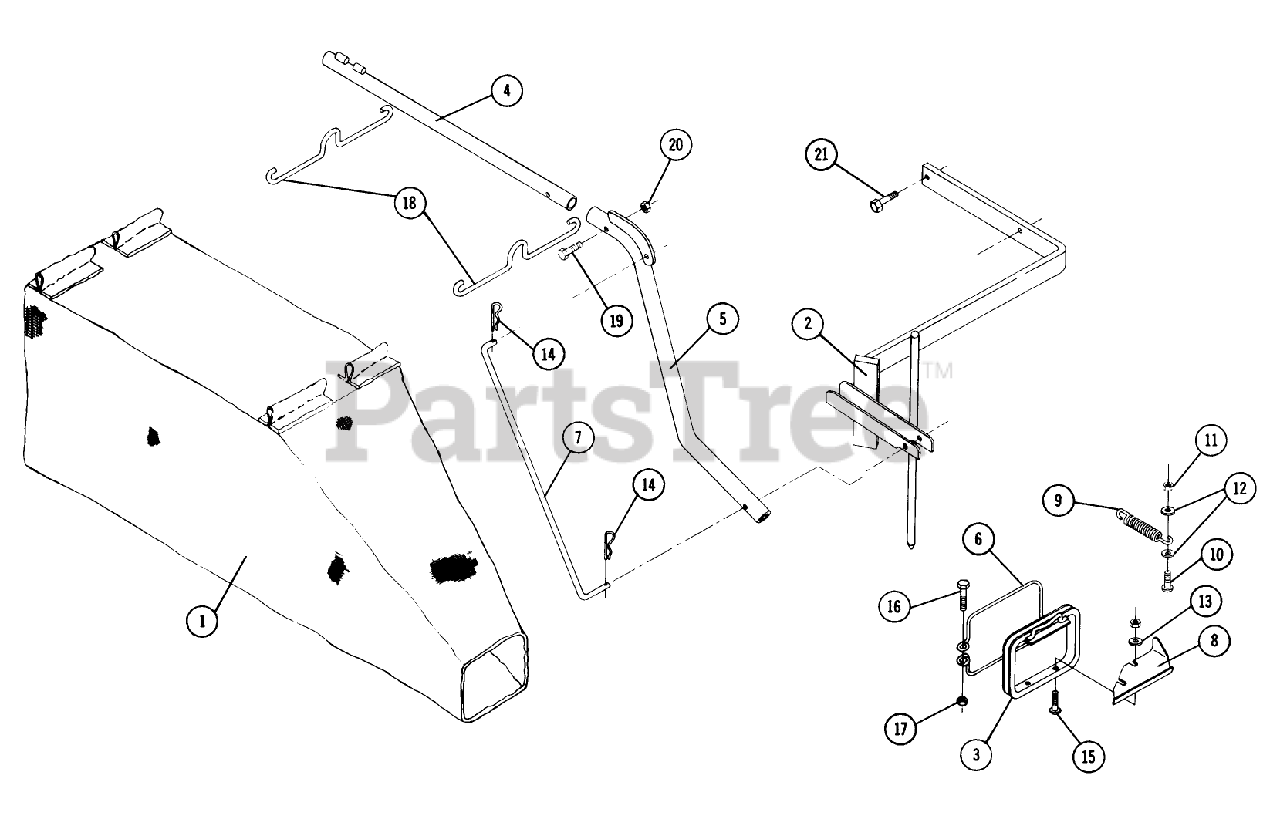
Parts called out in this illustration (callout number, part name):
2	Mounting Bracket
3	Bag Opening Frame
4	Upper Tube
5	Lower Tube
6	Wire Hoop
7	Link
8	Bottom Plate
9	SPRING R
10	Bolt 3/8-16 x 1 Pan Hd.
11	3/8-16 E.S.
12	Washer
13	Washer
14	Hairpin
15	Bolt 1/4-20 x 3/8 PHCR
16	Bolt 1/4-20 x 2
17	Nut-Nylok
18	Hook
19	Bolt 5/16-18 x 11/4
20	Nut-Nylok
21	Bolt 3/8-16 x 1 1/4 Swage
21	Bolt Hex 5/16-18
